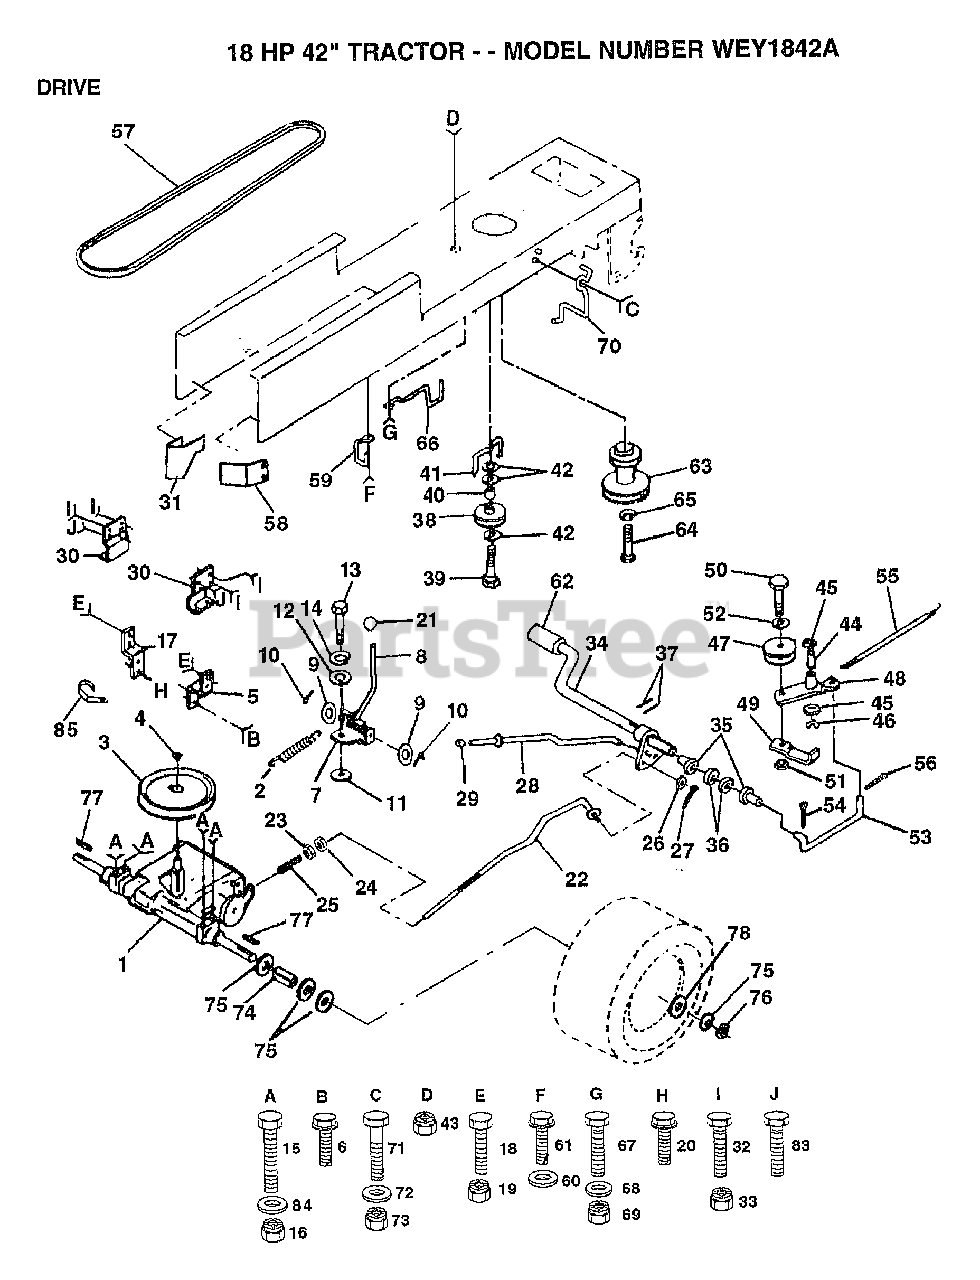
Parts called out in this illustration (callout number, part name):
3	"PULLEY,TRANSAXLE"
5	STRAP TORQUE
6	SCREW
8	SHIFT ROD
9	WASHER
10	PIN COTTER 1/8
11	WASH-SHFT PLT LT
12	WASHER LT
14	LOCKWASHER
15	BOLT HEX
17	STRAP TORQUE
20	SCREW
21	KNOB T (1/2-HOLE)
22	BRAKE ROD
23	NUT
24	NUT
25	SPRING ROD LT
26	WASHER
27	COTTER PIN
28	BRAKE PARK ROD
29	PLUNGER CAP T
30	TRANSAXLE MTG BKT
31	"KEEPER,BELT LH"
32	BOLT
35	NYLON BEARING
36	WASHER LT
38	PULLEY.IDLER.FLAT
39	BOLT
40	SPACER T
41	BELT KEEPER LT
42	WASHER
44	"LY, BEARING"
45	WASHER LT
46	KLIP RING
48	ARM IDLER
49	RETAIN BELT
52	WASHER
53	"LINK, CLUTCH T"
54	COTTER PIN
55	"SPRING, RETURN LT"
56	COTTER PIN
57	BELT-V
58	"KEEPER,BELT RH"
60	WASHER
61	SCREW
62	PEDAL COVER T
64	BOLT
65	LOCKWASHER
66	KEEPER.BELT.ENG.L
67	BOLT
68	WASHER
70	KEEPER BELT ENG
71	BOLT
72	WASHER
74	SPACER LT
75	WASHER
76	E-RING LT
77	SQUARE KEY
78	WASHER
83	SCREW
84	WASHER M
85	CLIP T
